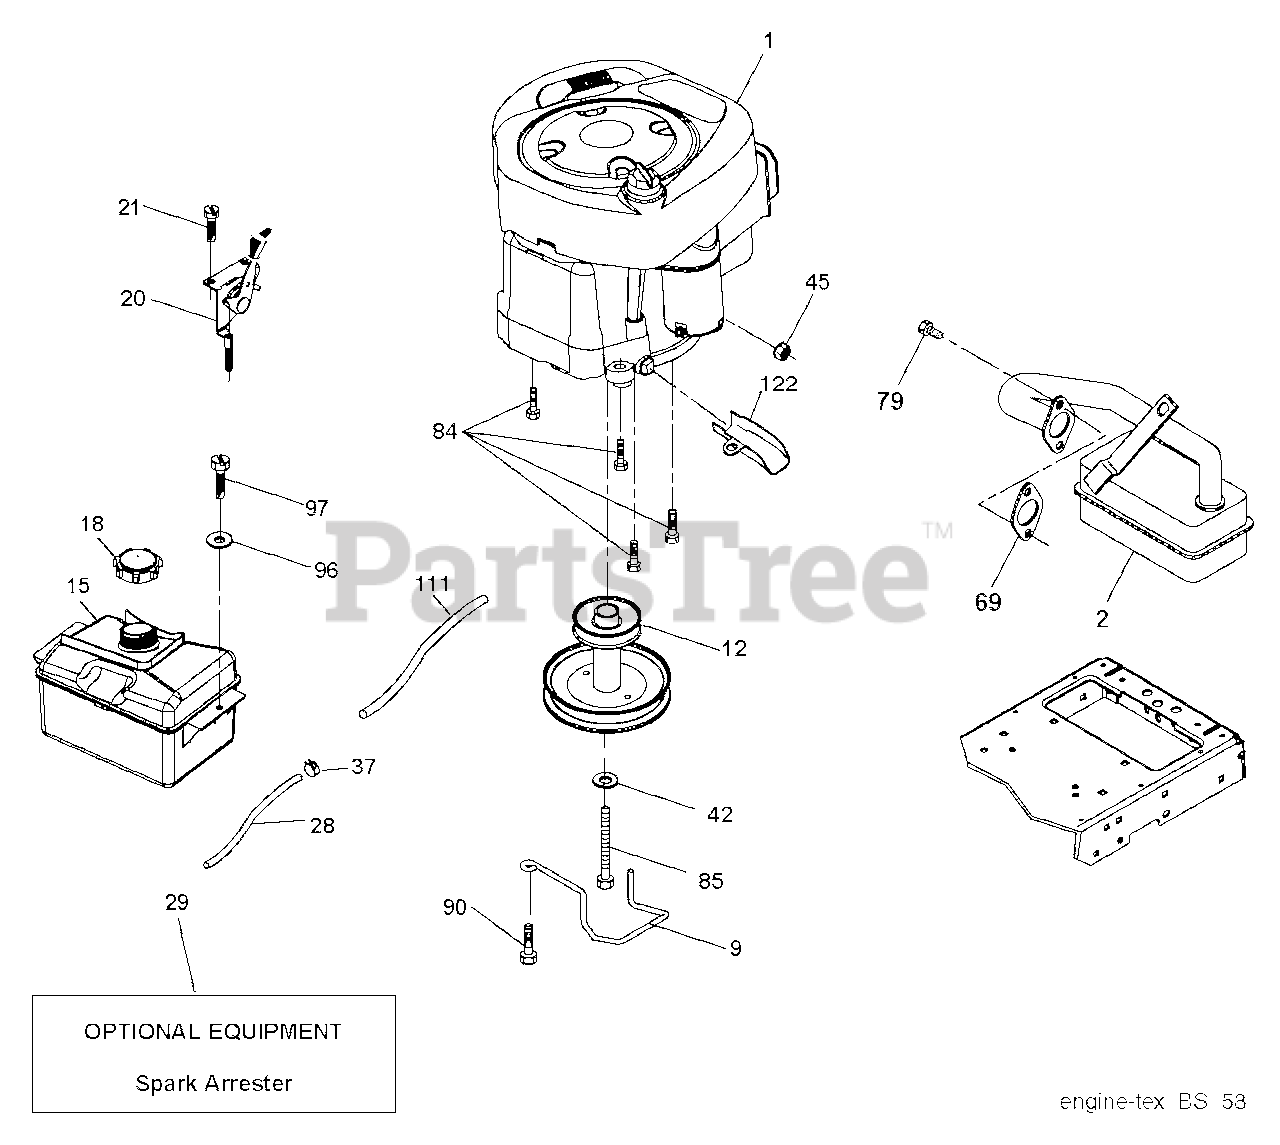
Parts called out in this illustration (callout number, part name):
1	Poulan TBD
2	MUFFLER.LT.BRIGGS.14HP.IC/OHV
9	KEEPER.BELT.ENGINE.3.25
12	PULLY ENGINE
15	TANK.ASM.1.5GAL.FRT.W/CAP.EPA
18	CAP.2.25'.VENTED.RATCHET.EPA
21	SCREW.#10 X 0.750.BOS (2 2)
28	LINE.FUEL.20"FRONT.EMI
29	KIT.SPARK ARRESTOR(392390 B&S)
37	HOSE CLAMP
42	LOCKWASHER
45	NUT
79	SCREW.SOCKET HD.5/16-1
84	SCREW.3/8-16
85	BOLT HEX 7/16-20X4-1/4"
90	SCREW 3/8-16X1
97	SCREW HEXWSHR 1/4-20X3/4
111	RP PURGE LINE
122	EXTENSION DRAIN OIL
